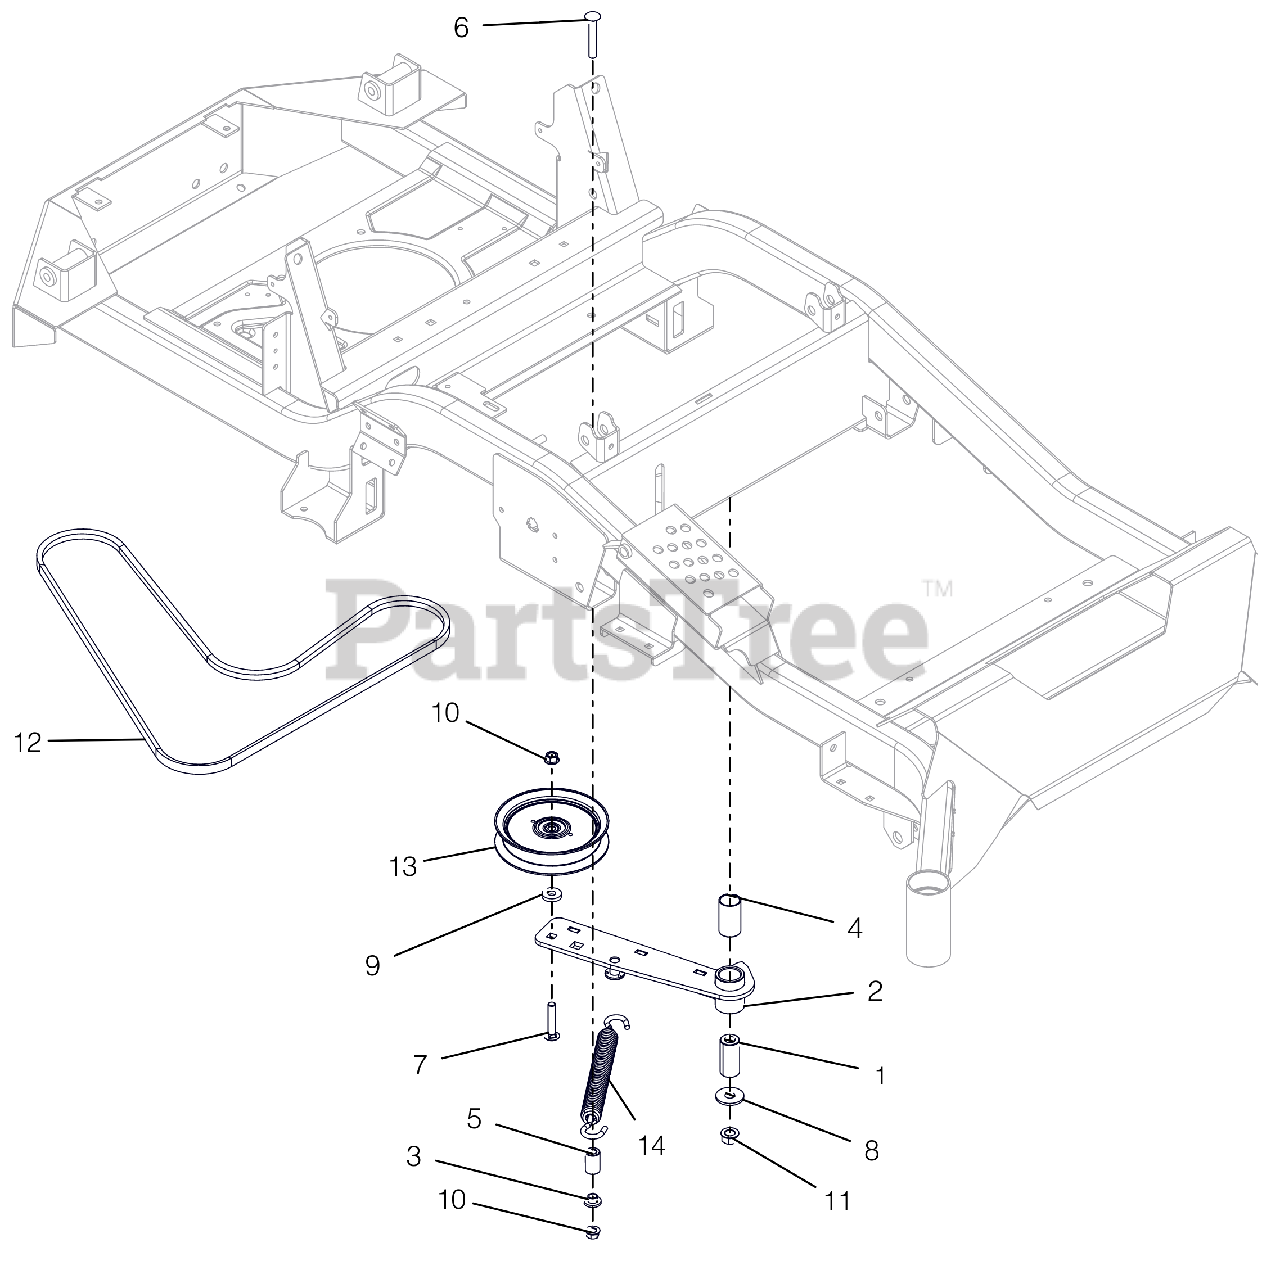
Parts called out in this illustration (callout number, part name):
1	BSHG, SPCR .502X.997X2.03 PM
2	WLDMT, HYDRO DRIVE IDLER ARM
3	BSHG-FLG .385X.500X.875X.406
4	BSHG, 1.00X1.125X1.937
5	BUSHING, SLV .380X.750X1.190
6	BLT-RDHDSQSHK, 38-16X2.50 G5YZ
7	@BLT-RDHDSQNK .38-16X2.00 G5YZ
8	WSHR-FL-STL.511X1.441X.125 YWZ
9	WSHR-FL-STL .406X1.00X.188 YWZ
10	@NUT-LK-TOP-FLG .38-16 YWZC
11	@NUT-LK-TOP-FLG .50-13 YWZC
12	V-BELT, 4L-WRAPPED
13	IDLER, FLAT 5.00"
14	SPRING, EXTENSION
